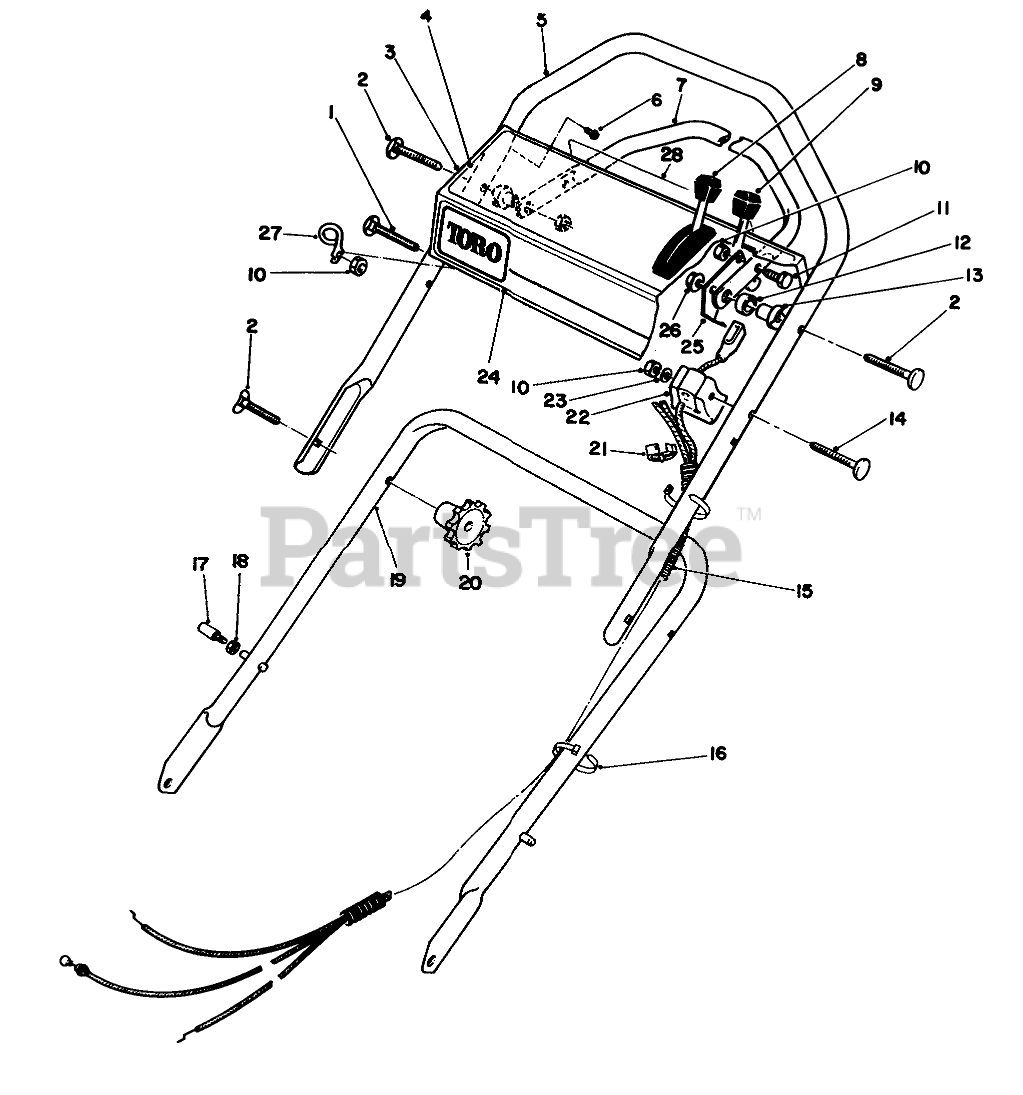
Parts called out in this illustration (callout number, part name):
1	HANDLE SCREW
2	5/16-18 X 2 HNDLE SCREW
3	Panel-Control (Incl. Ref. #4 & 29)
4	DECAL - INSTR (INT'L)
5	UPPER HANDLE, PVC DIP
6	SCREW-HWHTF
7	Bar-Control
8	Control-Traction (Bend Type #3) Sheath Lg. 46")(Wire Lg. 2")
9	THROTTLE CONTROL - R&S
10	NUT-LOCK, NI
11	SCREW-HH
12	SPACER-NYLON
13	SPACER-SUPPORT
14	HANDLE SCREW
15	CONT. CABLE COVER
16	TIE-CABLE
17	HANDLE PIN
18	NUT-LOCK, NI
19	LOWER HANDLE ASM
21	FITTING-RING
22	SUPPORT-CABLE
23	WASHER-FLAT
24	DECAL - TORO PANEL
25	LEVER-CONTROL
26	NUT-LOCK, NI
27	Guide
28	DECAL - PANEL, REAR
